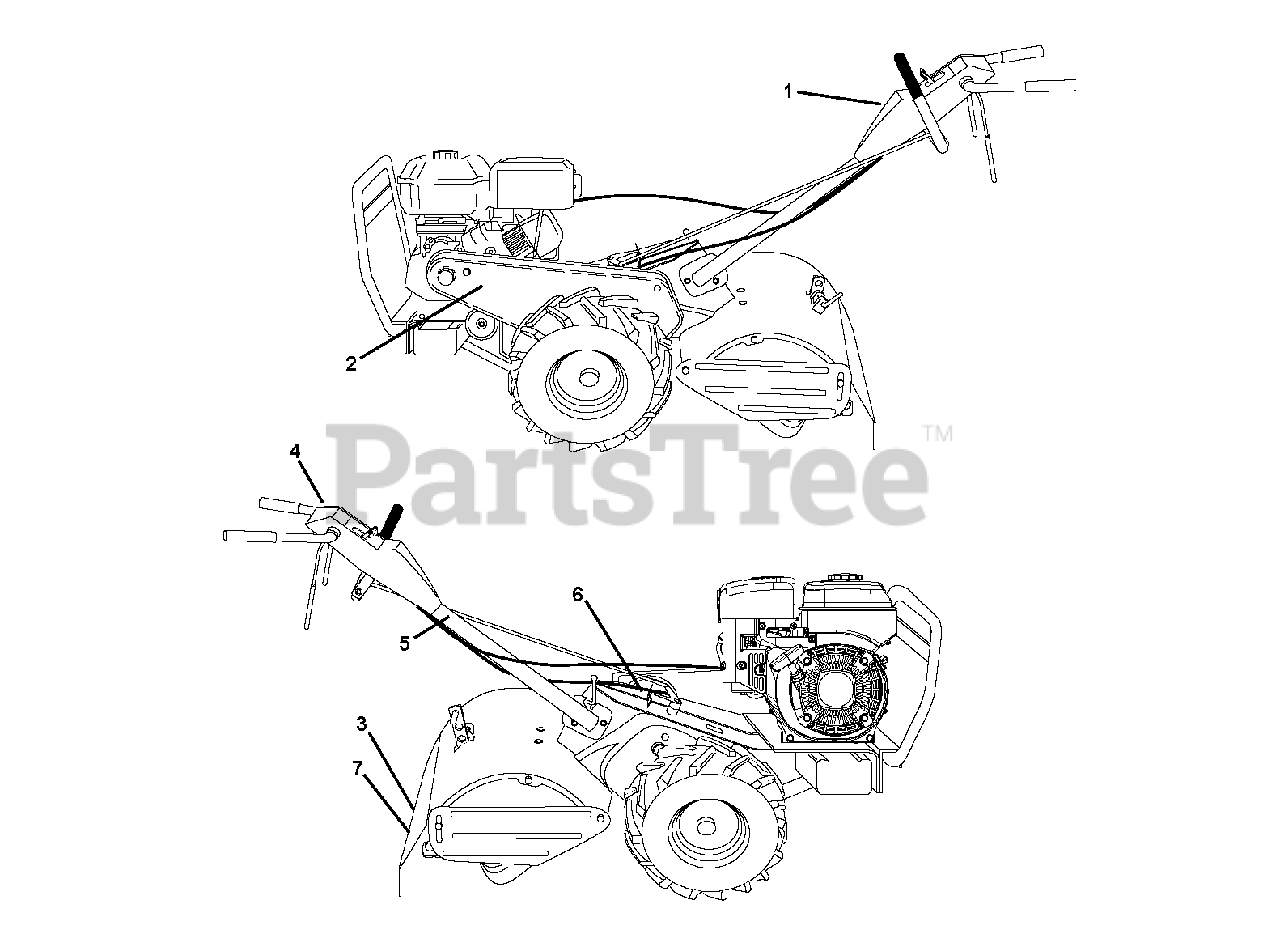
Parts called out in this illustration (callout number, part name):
2	RP.DECAL.BADGE.170MM.TEXTLOGO
3	DECAL EUROPE STANDARD CE
4	Decal, Console INS CRT
5	DECAL.PLACEMENT.HAND.SYMBOLS
6	DECAL, SHIFT INDICATOR
7	DECAL.WARNING.4-SYM.TILLER.INT
